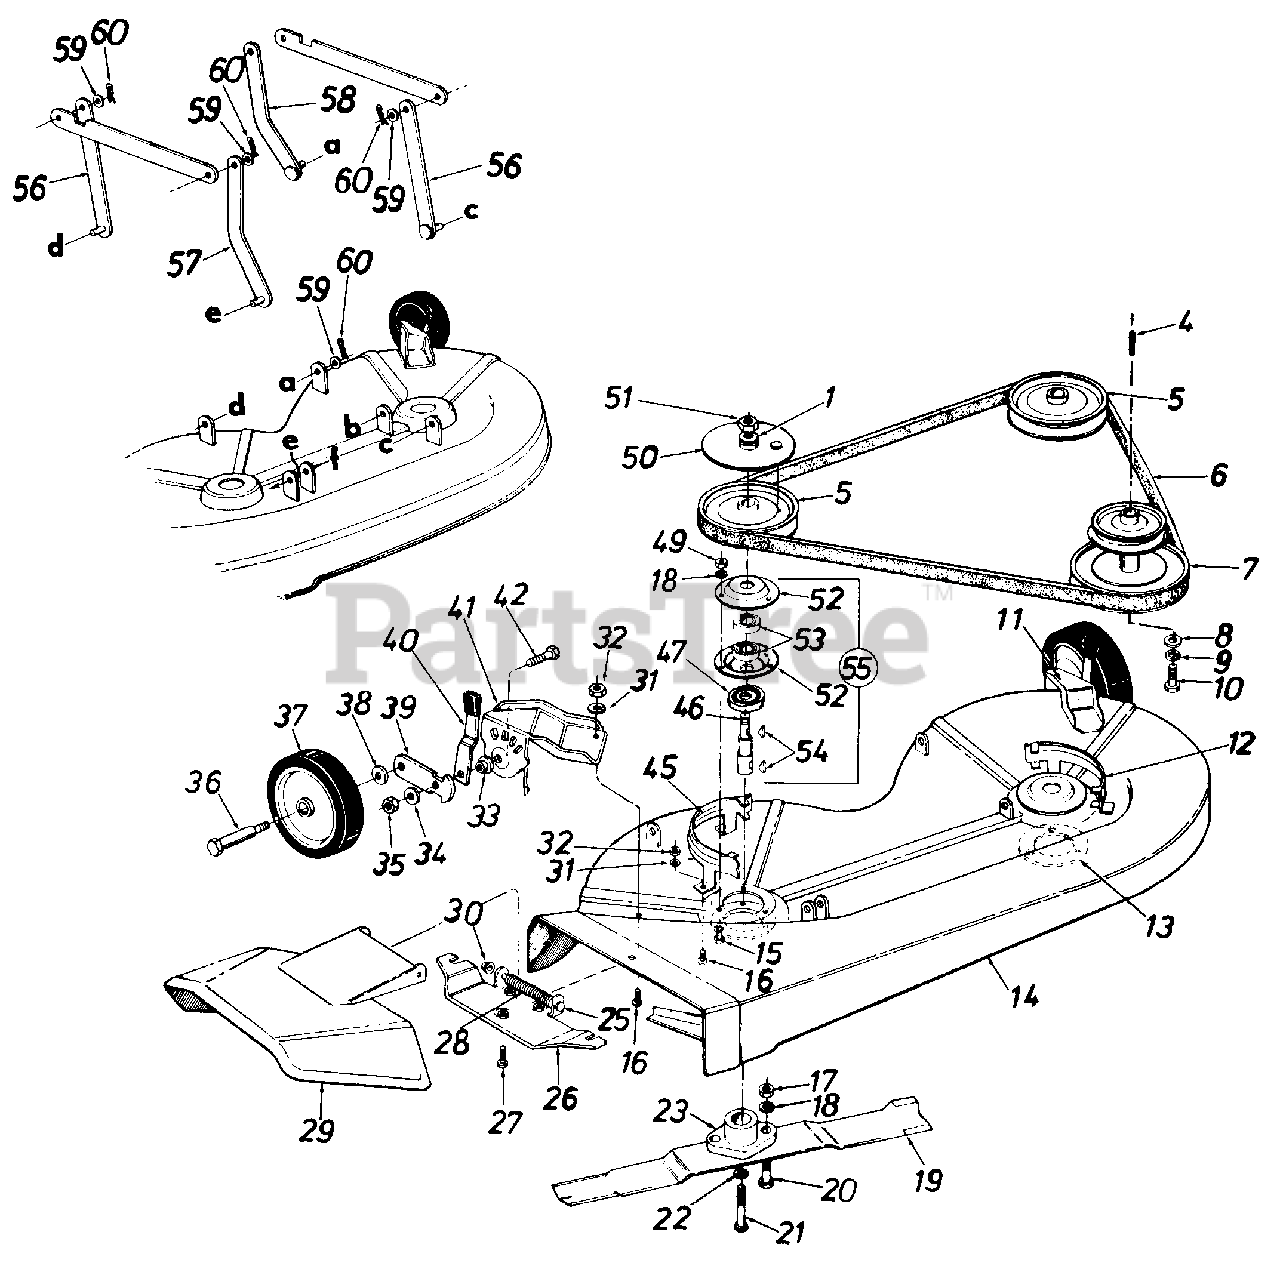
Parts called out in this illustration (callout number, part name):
1	L-Wash. 5/8" I.D.
4	Sq. Key 1/4 x 1/4 x 2.0" Lg.
5	Pulley 4.75" O.D.
6	"V"-Belt 21/32 x 67" Lg.
7	See Lawn Tractor Manual
8	Fl-Wash. 7/16" I.D. x 1.25 O.D. x .180
9	L-Wash. 7/16" I.D.
10	Hex Bolt 7/16-20 x 1.50" Lg.
11	Wheel Brkt.-L.H.
12	Belt Guard-L.H.
13	Plate Deck Reinforcement
14	34" Deck Ass'y.
15	Hex Sems Bolt 5/16-18 x 1.00" Lg.
16	Hex Bolt 1/4-28 x .50" Lg.
17	Hex Nut 5/16-24 Thd.
18	L-Wash. 5/16" I.D.
19	17" Blade
20	Hex Bolt 5/16-24 x 1.00" Lg. (Grade 5)
21	Hex Bolt 3/8-24 x 1.50" Lg. (Grade 5)
22	L-Wash. 3/8" I.D.
23	Blade Adapter Kit
25	Hinge Pin
26	Adapter Plate
27	Hex Wash. Self-Tap Scr. 1/4-20 x .50" Lo.
28	Torsion Spring
29	Chute Cover Ass'y.-Comp.
30	Push Nut 1/4" Rod
31	L-Wash. 1/4" I.D.
32	Hex Nut 1/4-28 Thd.
33	Shld. Spacer
34	Bell-Wash. .400" I.D. x 1.13"
35	Hex Top L-Nut 3/8-16 Thd.
36	Shld. Bolt .498" Dia. x 1.53"
37	Plastic Wheel 5.0" x 1.38"
38	Bell-Wash. .400" I.D. x .88"
39	Pivot Bar
40	Spring Lever Ass'y. w/Knob
41	Wheel Brkt.-R.H.
42	Hex Bolt 3/8-16 x 1.00" Lg.
45	Belt Guard-R.H.
46	Blade Spindle
47	Bearing Shield
49	Hex Nut 5/16-18 Thd.
50	Brake Disc
51	Hex Jam L-Nut 5/8-11 Thd.
52	Bearing Housing
53	Ball Bearing .787" I.D. x 1.85" O.D.
54	#6 Hi-Pro Key 5132" x 518" Dia.
55	Blade Spindle Ass'y.
56	Link Deck Hanger Assy.
57	Link Deck Hanger Ass'y.
60	Inter. Cotter Pin .50" Dia.
